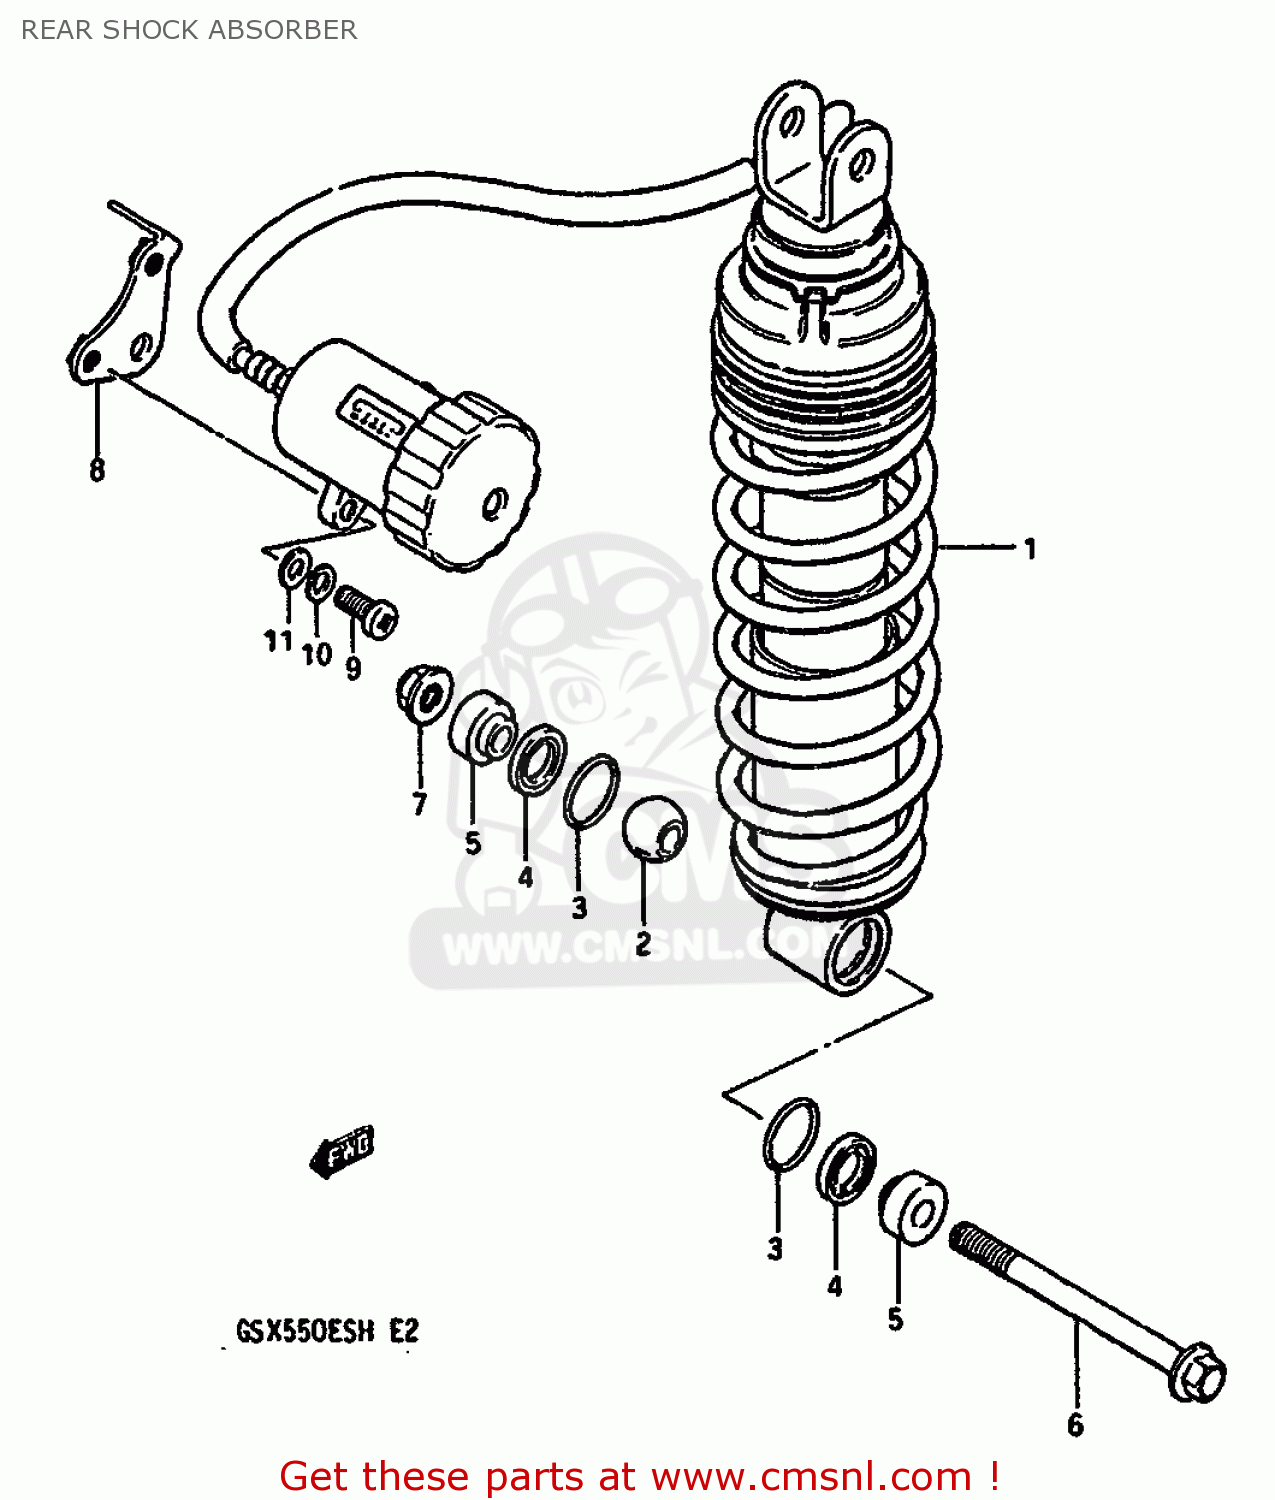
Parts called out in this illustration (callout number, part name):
1	SHOCK ABSORBER, REAR
2	BEARING,REAR SHOCK ABSORBER
3	RING
4	SEAL,DUST
5	COLLAR
6	BOLT(10X115)
7	NUT
8	BRACKET,RESERVOIR TANK
9	SCREW
10	WASHER,LOCK
11	WASHER
